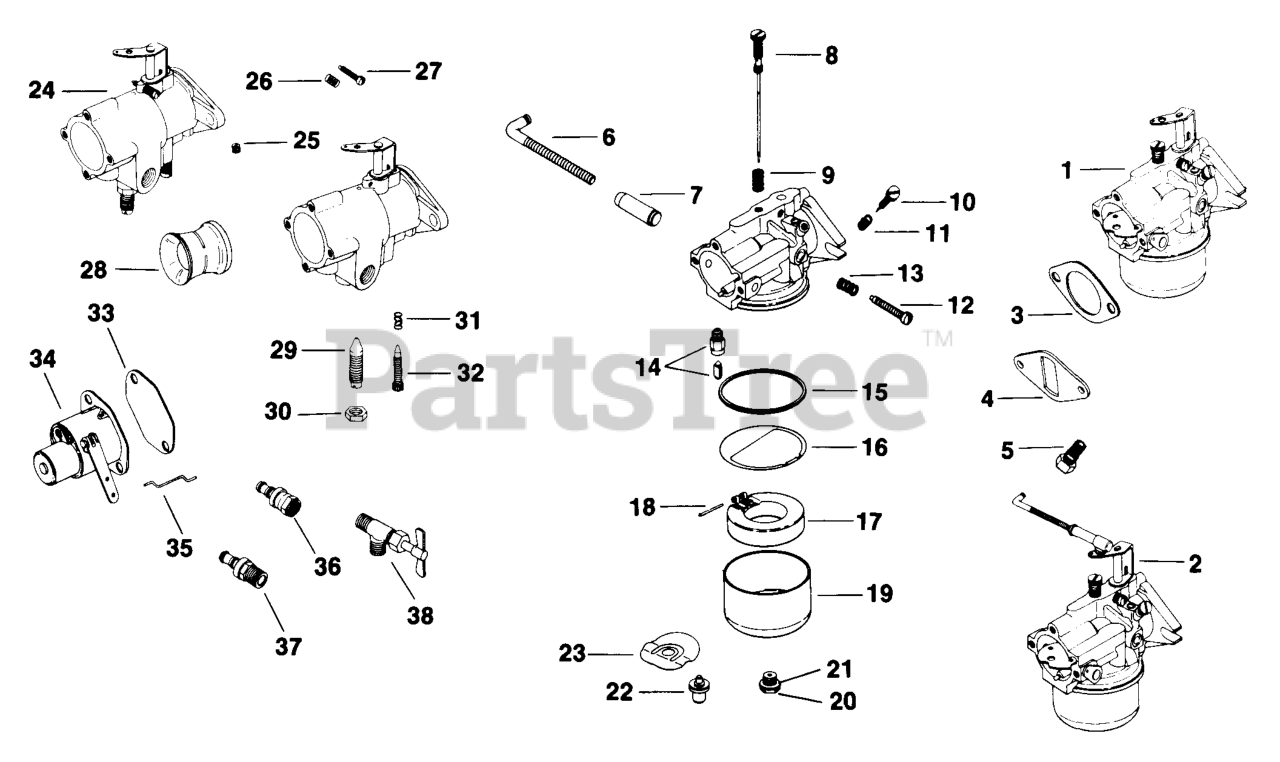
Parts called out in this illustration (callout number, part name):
3	GASKET, CARBURETOR
5	SCREW, SLT HD 5/16-18X1" - DISCONTINUED
24	CARBURETOR
27	SCREW, SPECIAL
31	SPRING - DISCONTINUED
32	SCREW - DISCONTINUED
